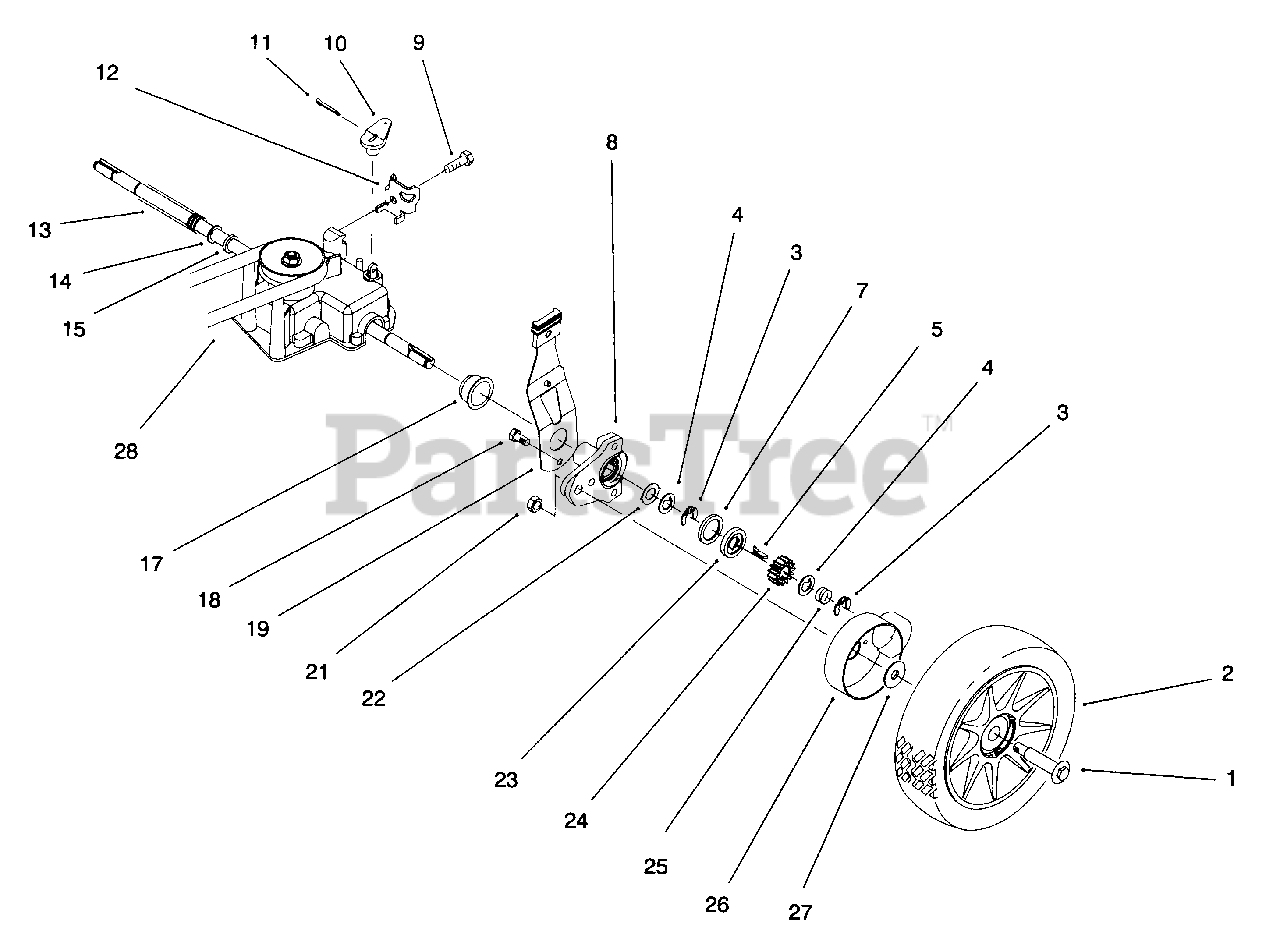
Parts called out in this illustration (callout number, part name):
1	Bolt-Shoulder
2	Wheel & Tire Ass'y-8"
3	Ring-Retaining
4	Washer-Thrust Keyed
5	Key-Rocking L.H.
7	Ring-Friction
8	Height Adj. Arm Ass'y-Rear
9	Screw-Tapping
10	Lever-Shift
11	Pin-Cotter
12	Retainer-Cable
13	Cover-Drive Shaft
15	Washer-Flat
18	Screw-Hex Hd. Cap
19	Spring Arm Ass'y-Rear L.H.
21	Nut-Lock
22	Washer-Thrust
24	Gear-Pinion
25	Spring-Compression
26	Cover-Wheel
27	Washer-Stepped
